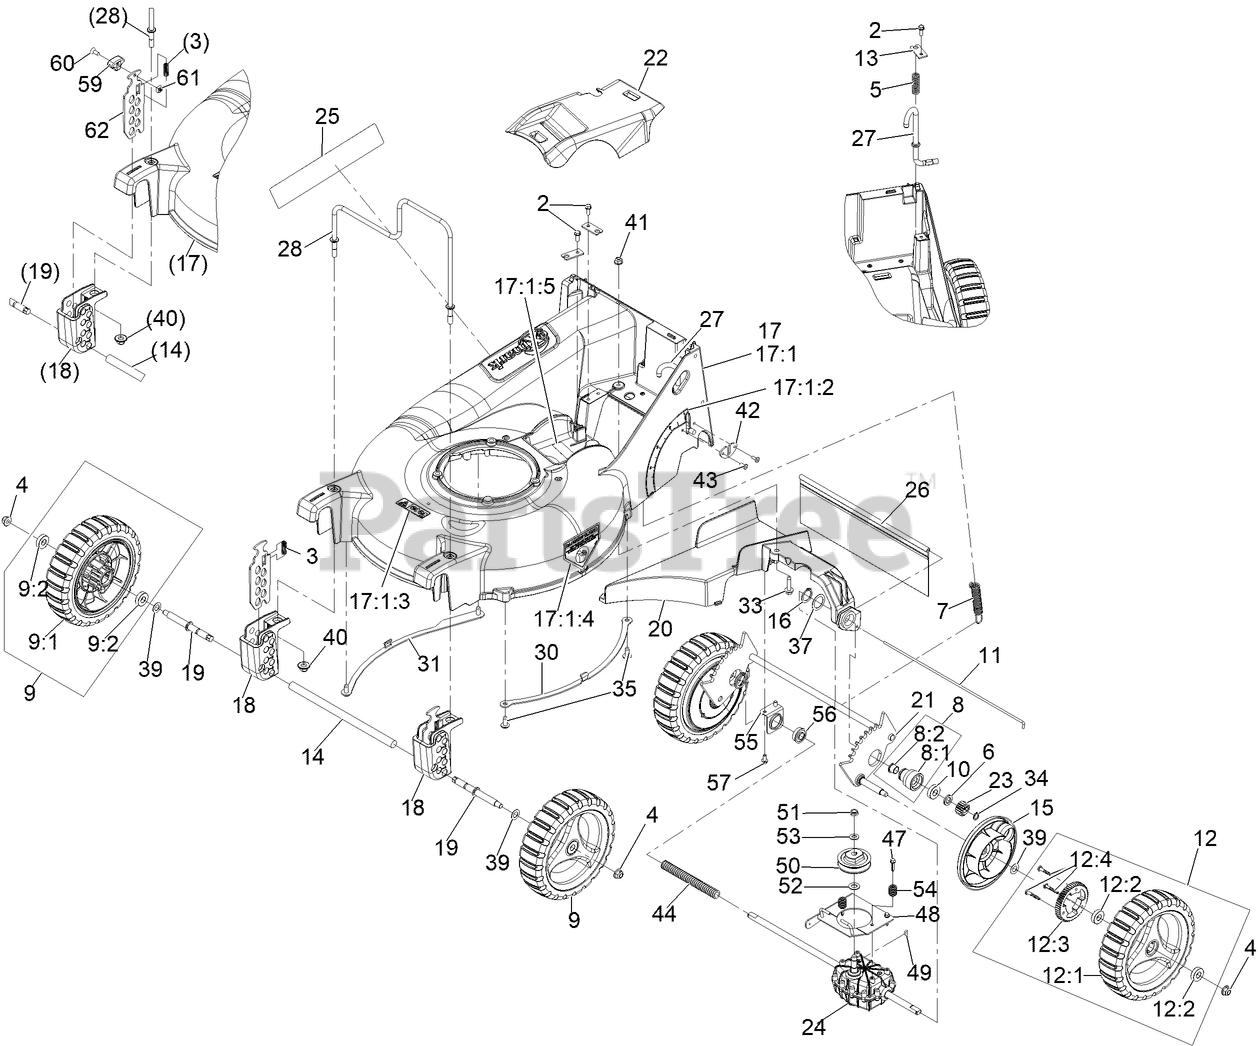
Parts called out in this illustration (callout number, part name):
2	SCREW-HWH
3	SPRING-COMPRESSION
4	NUT-HF, NI
5	SPRING-COMPRESSION
6	SPACER-BUSHING
7	SPRING-EXTENSION
8	HOUSING ASM
8:1	HOUSING-BEARING
8:2	BEARING-FLANGE
9	WHEEL ASM, 9" W/BEARINGS
9:1	WHEEL ASM, 9
9:2	BEARING-BALL
10	BEARING-BALL
11	ROD,SHIELD
12	WHEEL ASM, 9 W/GEAR
12:1	WHEEL ASM, 9
12:2	BEARING-BALL
12:3	GEAR-WHEEL, 52T
12:4	STUD-DRIVE
13	BRACKET,MOUNT
14	ROD,BUMPER
15	COVER,GEAR
16	RING-RETAINING
17	ASM-DECK EC21
17:1:2	DECAL-HEIGHT OF CUT
17:1:3	DECAL-WARNING, BLADE
17:1:4	DECAL-DANGER
17:1:5	DECAL-DANGER
18	BLOCK,FRONT QUADRANT
19	AXLE-WHEEL
20	Bracket-Transmission And Chute
21	WLD,REAR AXLE P21
22	COVER,BELT
23	GEAR-PINION, 15T
24	TRANSMISSION-HD, 4.5/1
25	DECAL-COMM 21 X-SERIES
26	SHIELD-TRAILING P21
27	ROD-HEIGHT ADJ P21
28	GUARD,ENGINE
33	SCREW-HWHTF
34	RING-RETAINING
39	WASHER-PLAIN
40	Nut-Nyloc 3/8-16 Flg
41	NUT-HF, NI
42	PLATE,WEAR
43	RIVET-BLIND
44	COVER-SHAFT-DRIVE
47	SCREW-SPECIAL
48	TRANSMISSION PLATE ASM
49	KEY-WOODRUFF
51	NUT-HEX
52	WASHER-THRUST
53	WASHER-FLAT
54	SPRING,COMPRESSION
55	MOUNT-BEARING
56	BEARING-BALL
57	SCREW-HWH
59	GRIP-HOC HANDLE
60	SCREW-HSFH
61	Square Nut 1/4-20,ATV CB
62	PLATE-ADJUSTER
